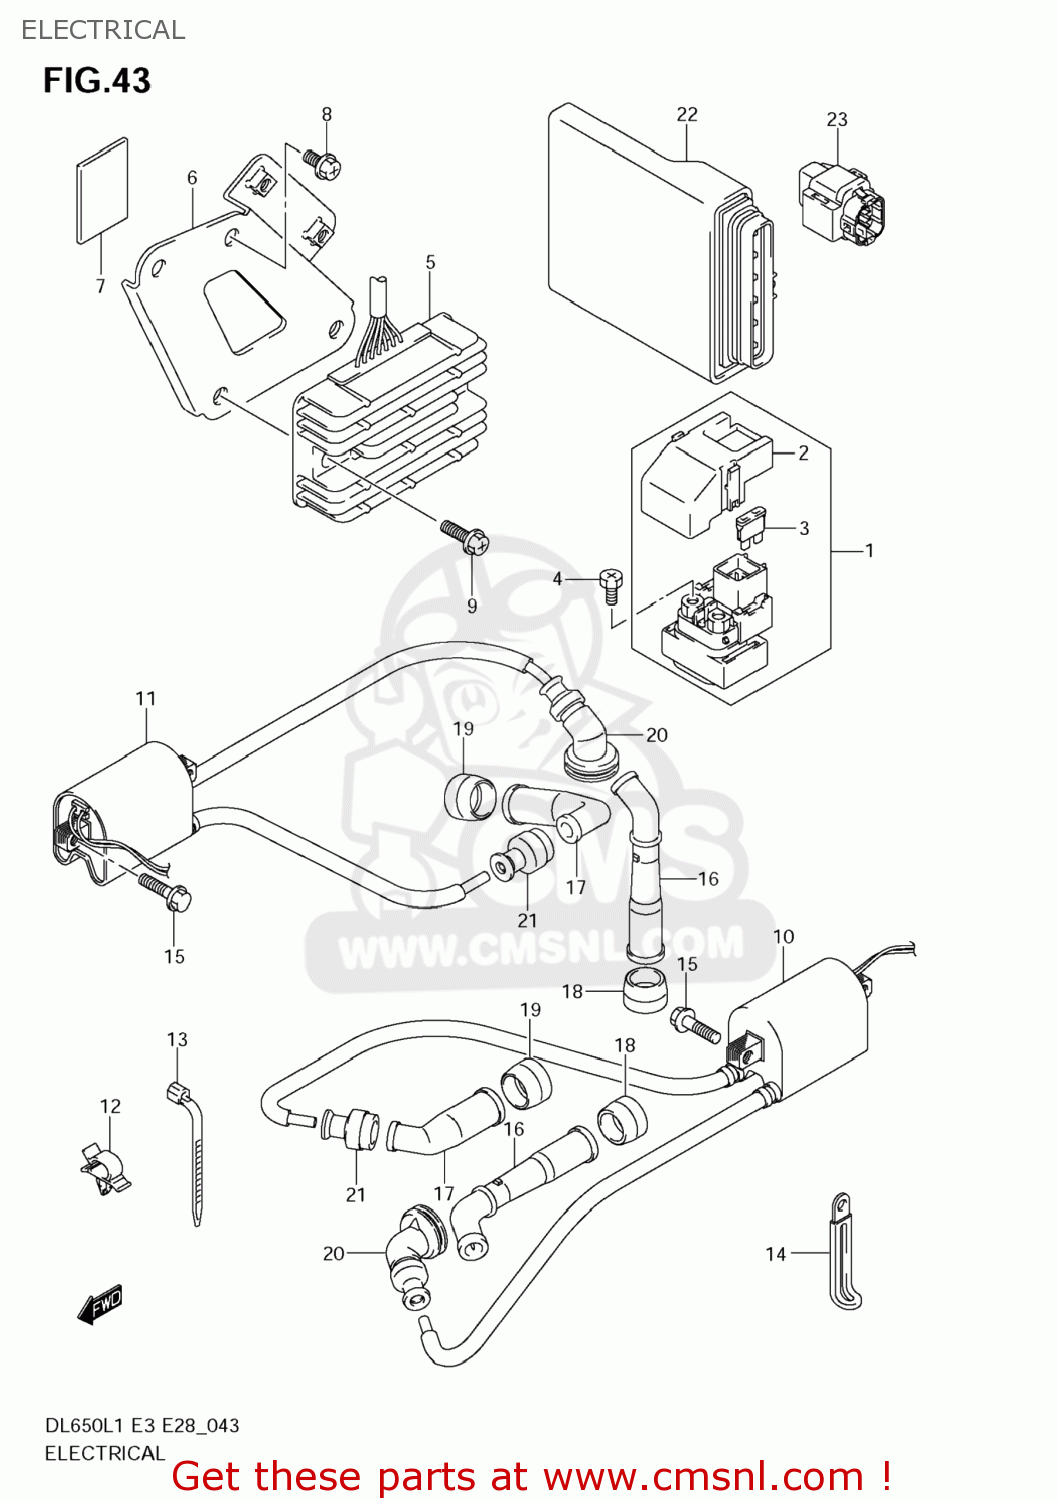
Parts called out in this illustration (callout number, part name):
1	RELAY ASSY,STARTING MOTOR
2	COVER
3	FUSE(30A)
4	SCREW(6X8)
5	RECTIFIER ASSY
6	BRACKET,RECT FTG
7	PROTECTOR,BATTERY
8	SCREW
9	SCREW
10	COIL ASSY,IGNITION FR
11	COIL ASSY,IGNITION RR
12	CLAMP
13	CLAMP(L:165)
14	CLAMP(L:45)
15	BOLT
16	CAP ASSY,SPARK PLUG
17	CAP ASSY,SPARK PLUG
18	SEAL,SPARK PLUG
19	SEAL,SPARK PLUG
20	SEAL,HIGH TENSION CORD CTR
21	SEAL,HIGH TENSION CORD
22	CONTROL UNIT,FI
23	SENSOR ASSY,FUEL CUT
